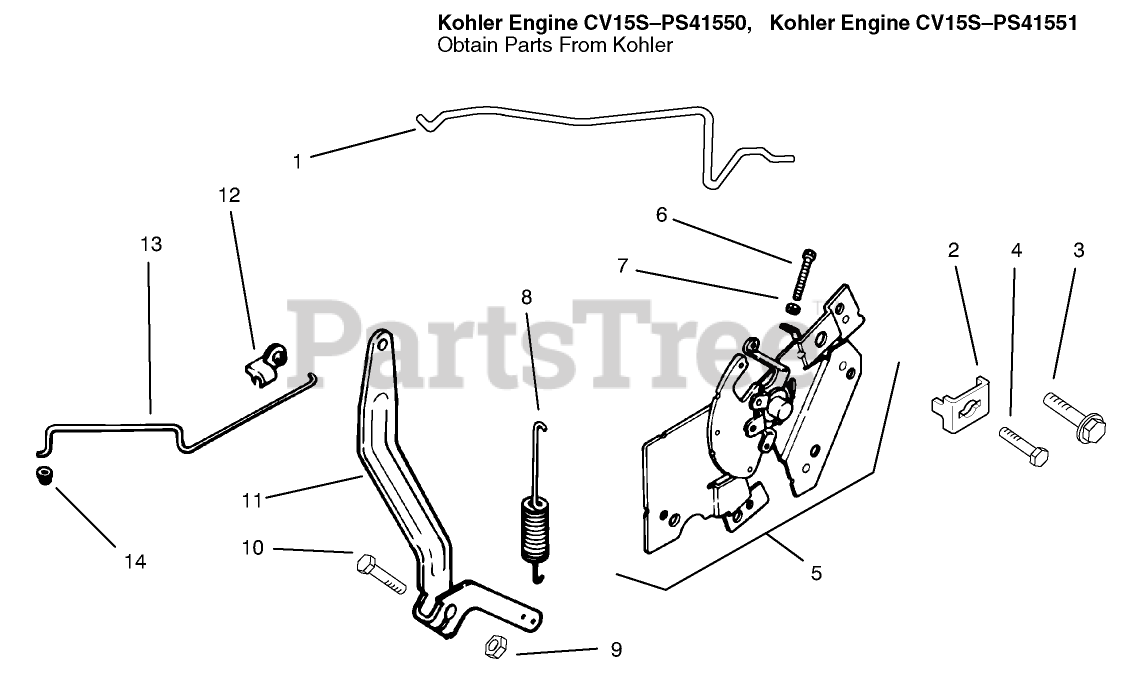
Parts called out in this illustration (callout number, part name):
1	Linkage-Choke (Only On: 72042,72043,72062,72063)
3	Screw Socket
4	Screw M5x0.8x16 (Only On: 72042, 72063, 72062, 72043)
5	Control-ASM INC 6-7 (Only On: 72042, 72063, 72062, 72043)
6	Screw-HHF M4x0.7x28 (Only On: 72042, 72063, 72062, 72043)
7	Nut
8	Spring-Governor (Only On: 72042, 72063, 72062, 72043)
11	Lever-Governor (Only On: 72042, 72063, 72062, 72043)
12	Bushing-Linkage
13	Linkage-Throttle (Only On: 72042, 72063, 72062, 72043)
14	Bushing
